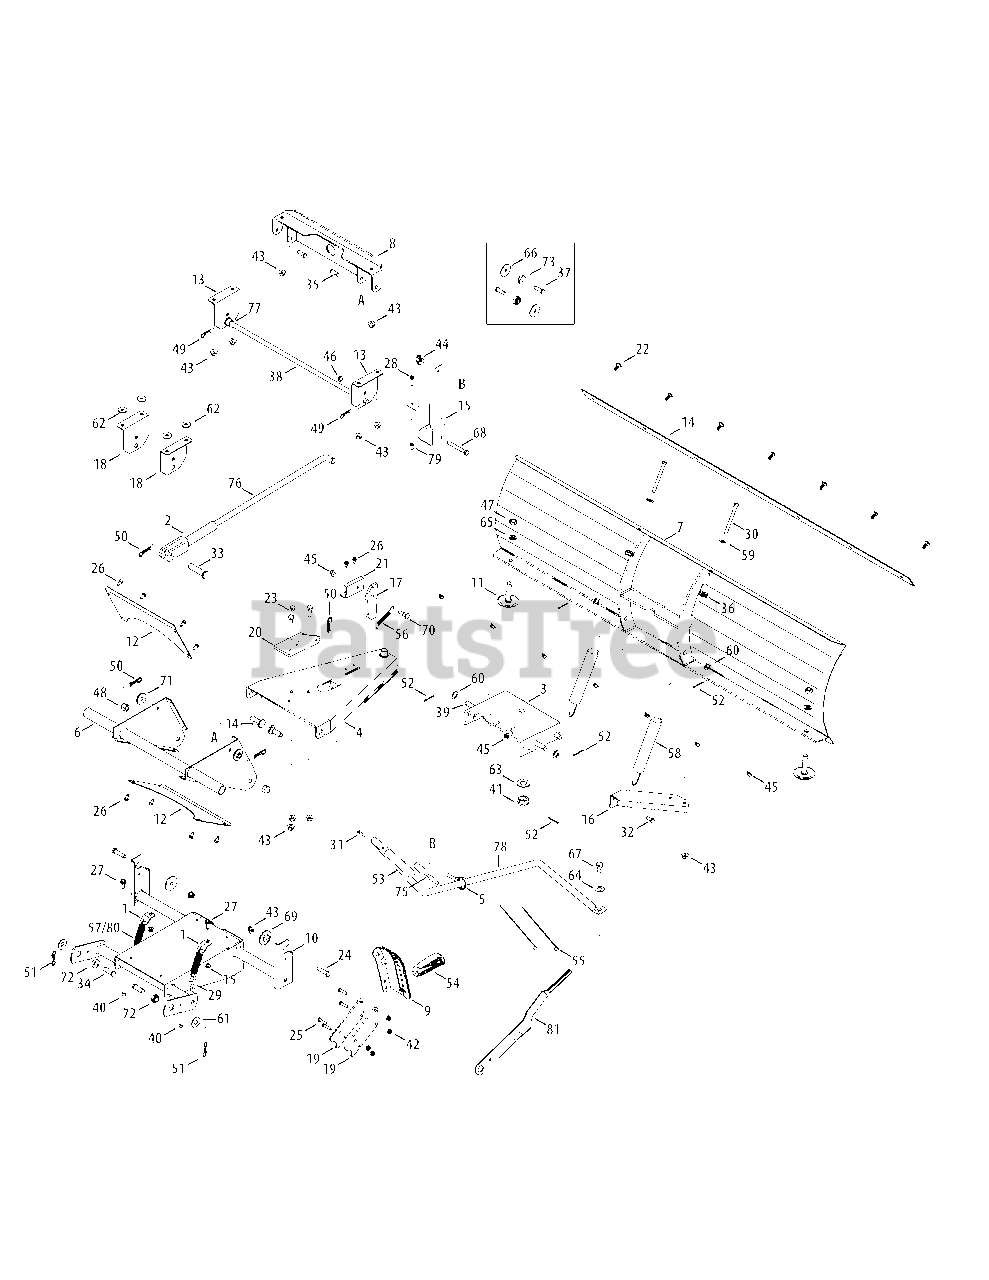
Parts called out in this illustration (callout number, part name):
1	Spring Mount Bracket
2	Clevis Adjustment Assembly
3	Blade Pivot Assembly
4	Blade Frame Assembly
5	Eyebolt Assembly
6	Bracket Assembly
7	52" Blade Assembly
8	Blade Mount Bracket Assembly
9	Blade Height Adj. Index Bracket
10	Lift Bracket Assembly
13	Mounting Bracket
14	52" Blade Scraper Plate
15	Handle Mount Bracket
16	RH Blade Adjustment Arm
17	Blade Lock Plate
18	Mount Bracket
19	Lift Arm Stiffener Bracket
20	Front Lift Bracket
21	Pivot Bracket
22	Carriage Bolt, 5/16-18 x .750
23	Hex Screw, 3/8-16 x 1.00
24	Hex Screw, 3/8-16 x 1.50
25	Hex Screw, 1/4-20 x 1.00
26	Hex Washer Screw, 1/4-20 x .50
27	Hex Washer Screw, 5/16-18 x .875
28	Hex Washer Screw, 1/4-20 x 1.000
29	Eye Bolt, 1/4-20
30	Hex Screw, 5/16-18 x 3.50
31	Machine Screw, #10-24 x 1.375
32	Hex Screw, 5/16-18 x .75
33	Clevis Pin, .625 x 2.40
34	Clevis Pin, .500 x 1.25
35	Clevis Pin, .375 x .969
36	Spring Insert
37	Clevis Pin, 3/8 x 1.123
38	Rod, .50 x 22.65
39	Rod, .50 x 10.428
40	Nut, 1/4-20
41	Slotted Nut, 3/4-16
42	Flange Lock Nut, 1/4-20
43	Flange Lock Nut, 3/8-16
44	Wing Nut, 5/16-18
45	Flange Lock Nut, 5/16-18
46	Jam Lock Nut, 3/8-16
47	Jam Nut, 1/2-13
48	Hex Lock Nut, 1/2-13
49	Click Pin, .092 x 1.64
50	Cotter Pin, .125 x 1.75
51	Bow-Tie Cotter Pin
52	Cotter Pin, 1/8 x 1.25
53	Foam Grip
55	Cable Tie, 3/16 x 7.4
56	Extension Spring, .38 x 3.25
58	Extension Spring, 1.25 x 6.7
59	Flat Washer, .349 x .879 x .063
60	Flat Washer, .530 x .930 x .050
61	Flat Washer, .531 x 1.250 x .100
62	Flat Washer, .385 x 1.000 x .135
63	Flat Washer, .760 x 1.500 x .120
64	Flat Washer, .570 x 1.120 x .062
65	Lock Washer, 1/2
66	Flat Washer, .406 x 1.500 x .105
67	Shoulder Bolt, 3/8-16 x .496 x .336
68	Shoulder Bolt, 3/8-16 x .500 x 2.38
69	Shoulder Spacer, .8840 x .190
70	Shoulder Screw, 5/16-18 x .405 x .435
71	Shoulder Spacer, 1.375 x .380 x .183
72	Shoulder Spacer, .50 x .75 x .170
73	Shoulder Spacer, .375 x .75 x .170
74	Shoulder Screw, 1/2-13 x .625 x .36
75	Blade Release Cable
77	Flange Bearing, .503 x .75
78	Blade Adjust Handle
79	Spacer, .258 x .50 x .50
81	Lift Handle
